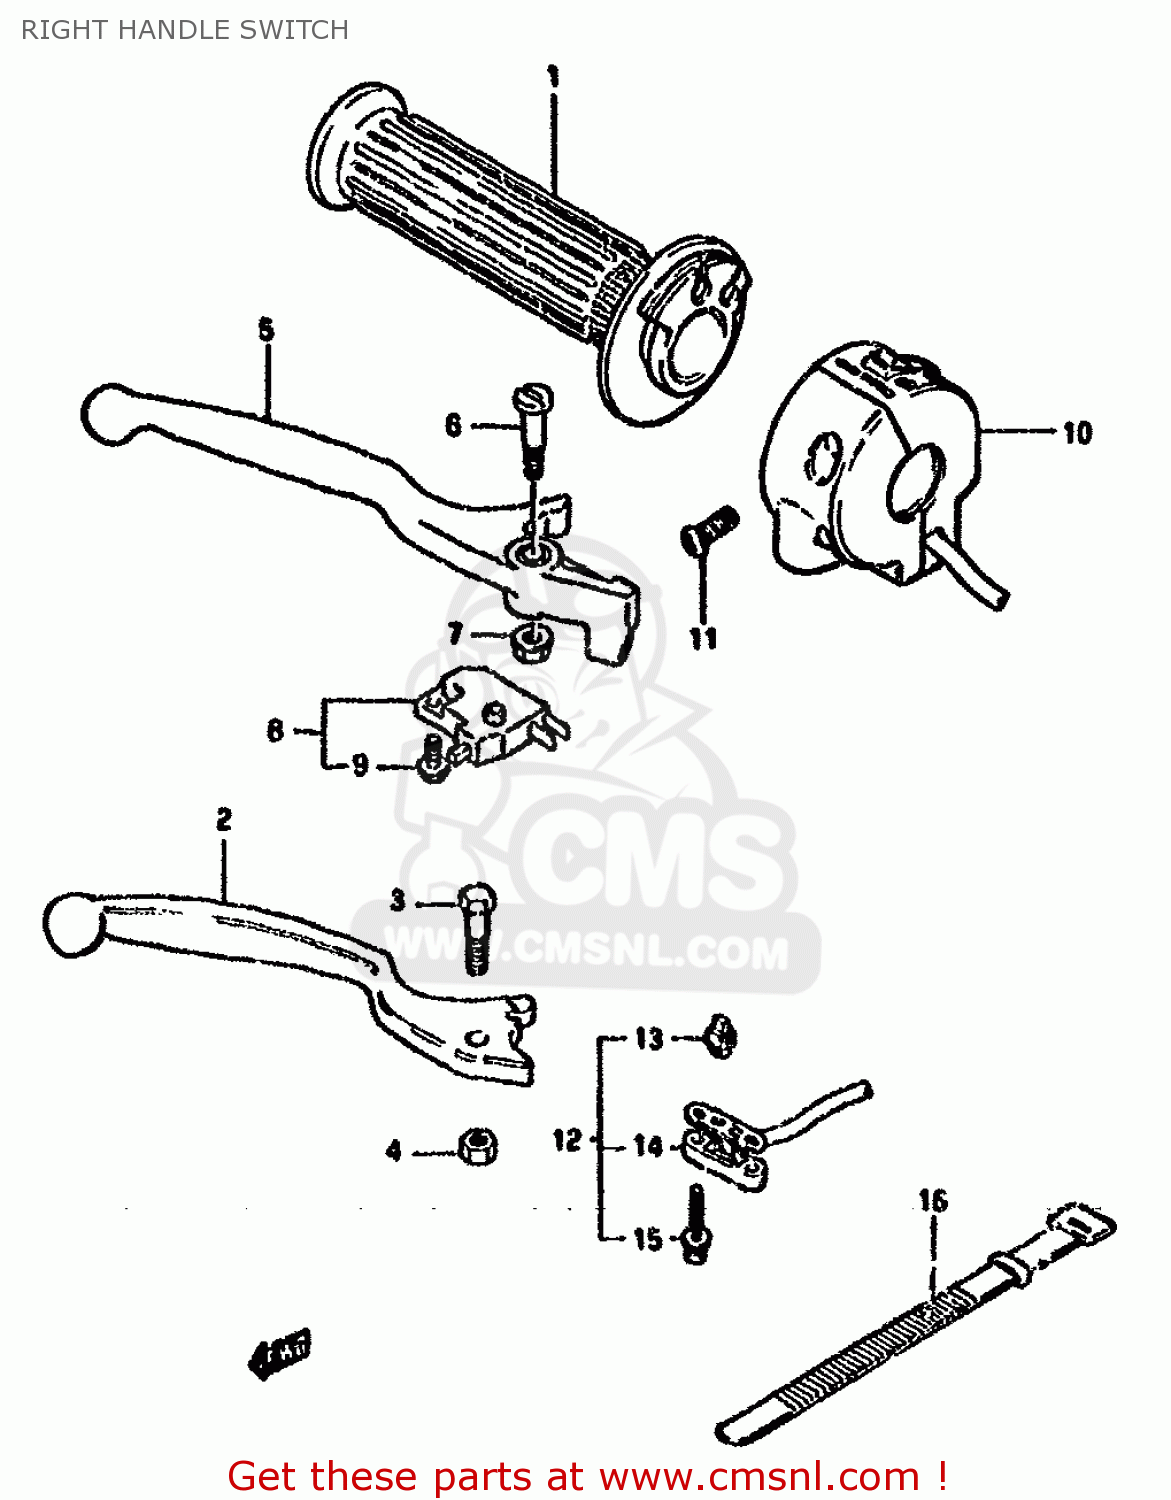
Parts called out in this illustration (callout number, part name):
1	GRIP,THROTTLE
2	LEVER,BRAKE
3	BOLT,LEVER PIVOT
4	NUT
5	LEVER,BRAKE
6	BOLT,LEVER PIVOT
7	NUT 6MM
8	SWITCH ASSEMBLY,STOP
9	SCREW
10	SWITCH ASSY,HANDLE,R
11	SCREW
12	SWITCH ASSY,ST
13	CONTACT,SWITCH
14	COVER,FR BK TERMINAL BASE
15	SCREW
16	CLAMP(L:120)
